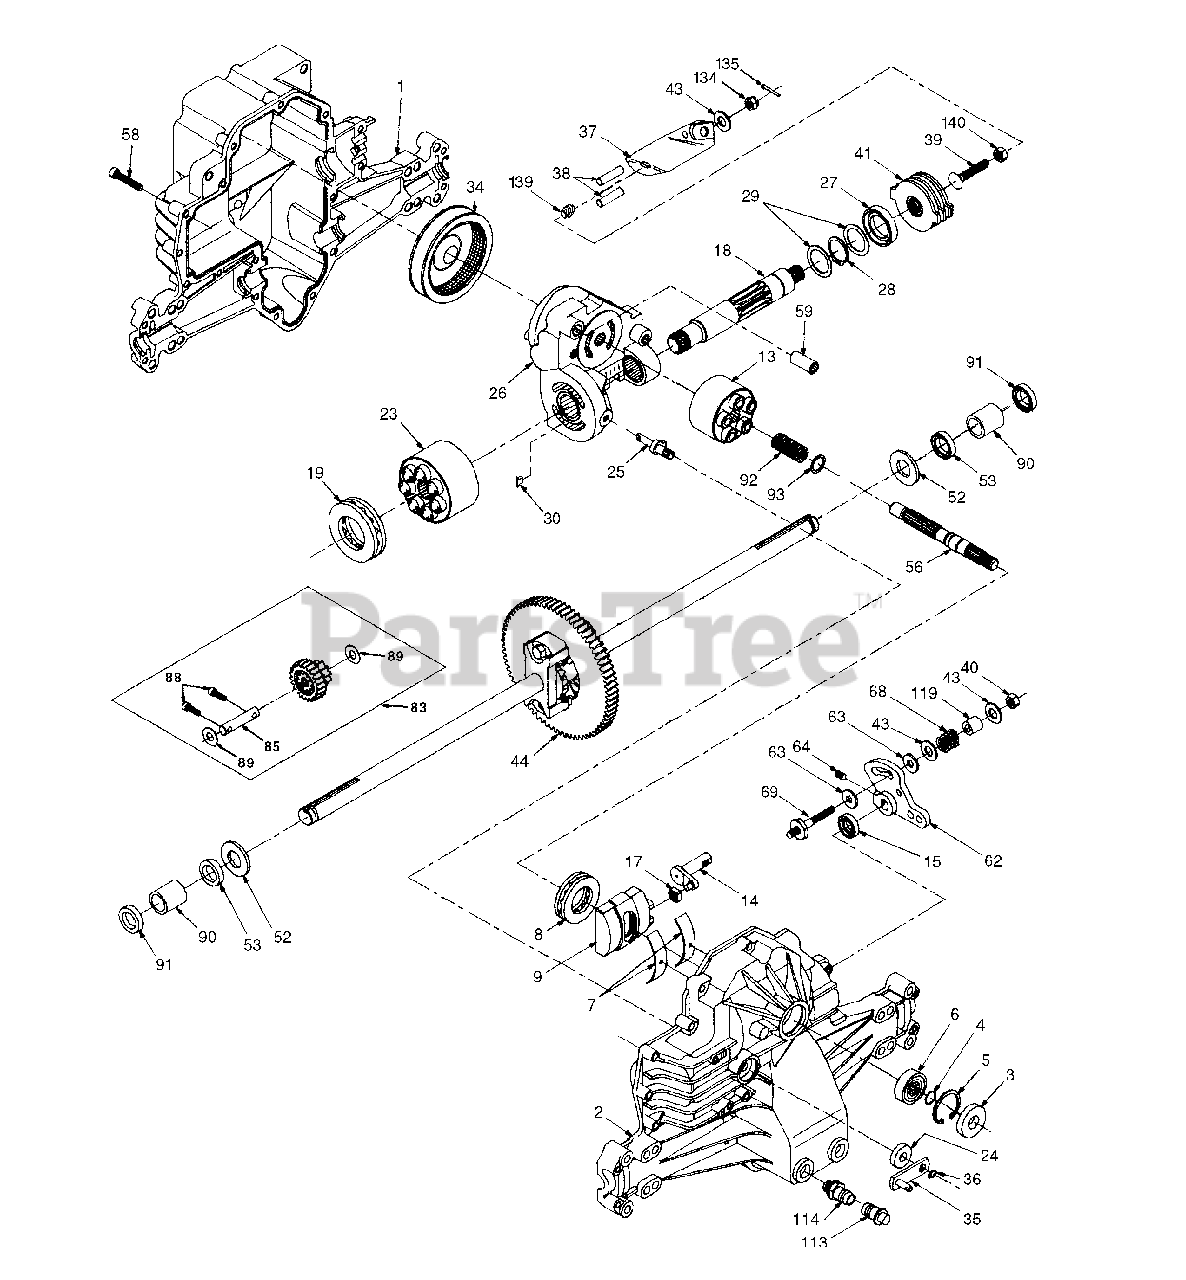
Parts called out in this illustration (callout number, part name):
1	Housing, Lower
2	Assembly, Upper Housing
4	Ring, Wire Retaining
5	Ring, Retaining
6	Bearing, Shaft Ball
7	Bearing, Cradle
8	Bearing, Thrust 30 x 52 x 13
9	Swashplate, Variable
13	Block, Cylinder Assembly
14	Arm, Trunnion
17	Guide, Slot
18	Shaft, Motor
19	Bearing, Thrust 42 x 68 x 16
23	Block, Cylinder Assembly
24	Seal, Lip 10 x 25 x 7
25	Actuator, Bypass
26	Center Section Assembly Kit
27	Seal, Lip 26 x 42 x 8
28	Ring, Retaining
29	Washer 26 x 35 x 1
34	Oil Filter Element
35	Arm, Bypass
36	Ring, Retaining
37	Arm, Actuating
38	Pin, Actuating
39	Bolt 5/16-24 x 1-3/4
40	Locknut, Hex 5/16-24 UNJC
41	Brake Rotor/Stator Kit
43	Washer 7/16 x 7/8 x .060
44	Differential Assembly
52	Washer 3/4 x 1.5 x .13
53	Seal .75 x 1.25 x .250
56	Shaft, Input
58	Bolt 1/4-20 x 1.38
59	Pin .5 OD x .43 ID x .750
62	Arm, Control
63	Puck, Dampener
69	Stud 5/16-24
83	Jackshaft Assembly
88	Screw, Cap
89	Washer 7/16 x 1 x 1/2
90	Sleeve Bearing
91	Seal, Wiper
92	Spring, Block
93	Washer, Block Thrust
113	Cap, Vent Assembly
114	Fitting, O-Ring Assembly
119	Spacer
134	Nut, Castle 5/16-24
135	Pin, Cotter
139	Spring, Compression
140	Nut, Hex 5/16-24
